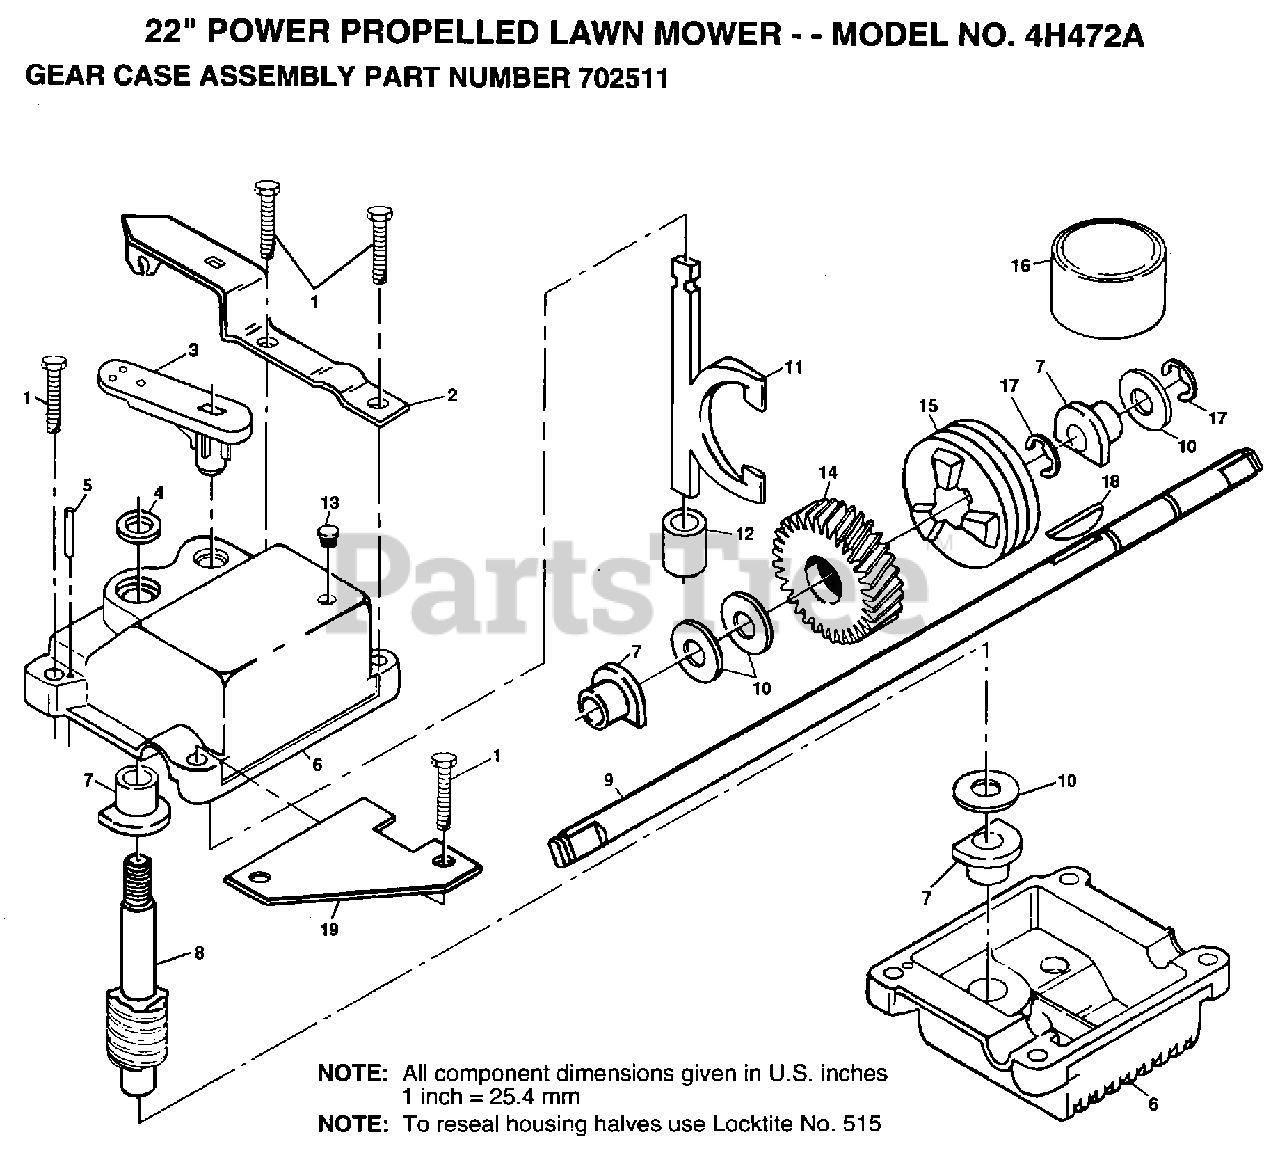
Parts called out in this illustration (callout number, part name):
1	SCREW.1/4-20
3	SHIFTER
4	SEAL
5	DRIVE LOK PIN
6	GEARCASE KIT
7	BEARING
8	SHAFT.WORM
9	SHAFT.DRIVE
10	THRUST WASHER
11	CLUTCH YOKE
12	BUSHING.GEAR BOX
13	PLUG PM
14	GEAR.HELICAL
15	CLUTCH JAW
17	RING T
18	HI PRO KEY
